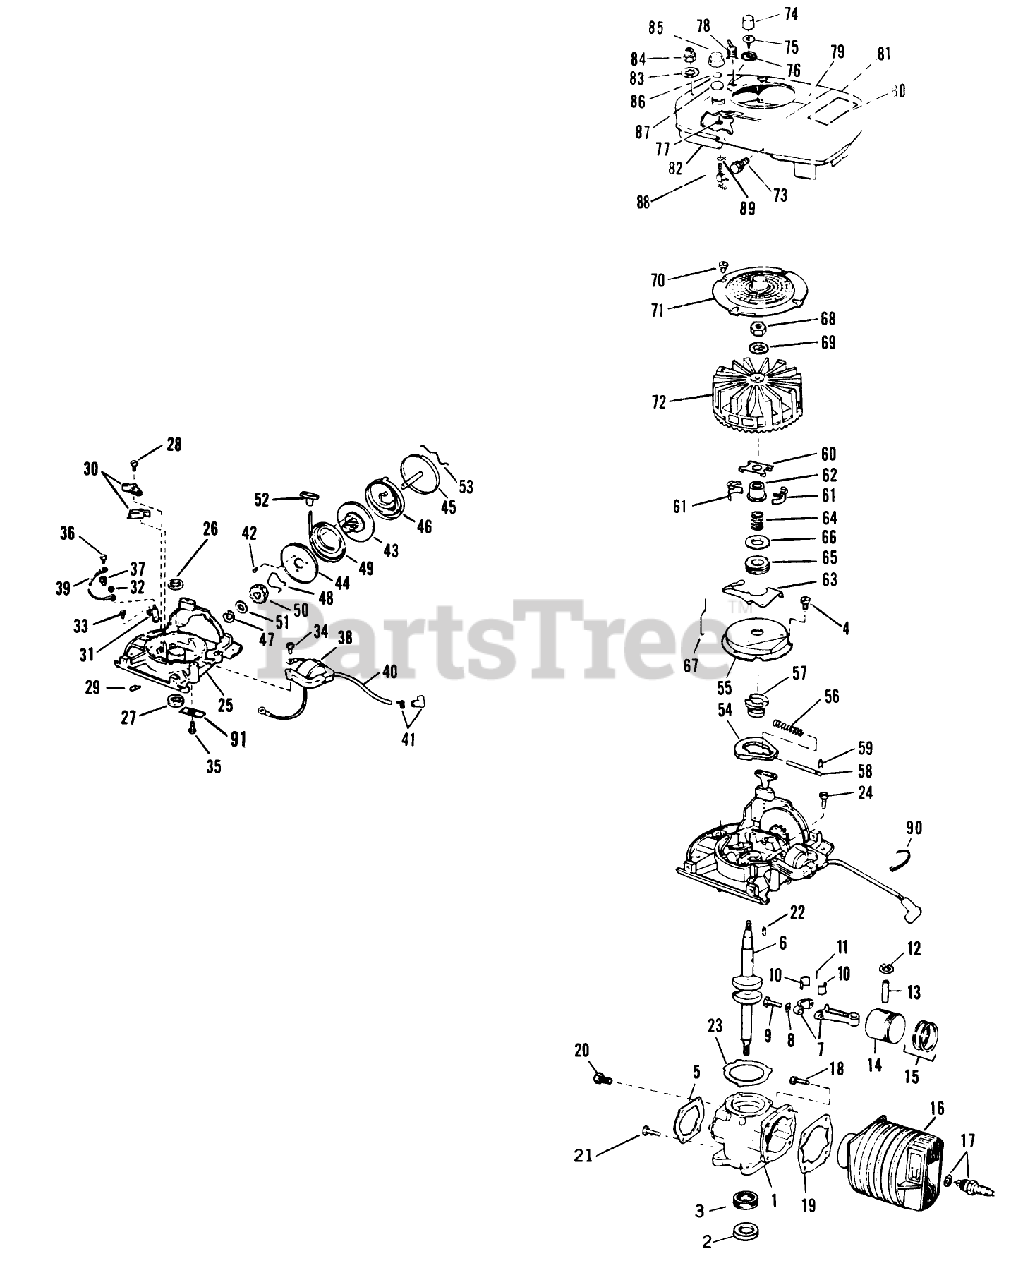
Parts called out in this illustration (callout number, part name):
3	BEARING AY. S
4	SCREW S
5	GASKET S
10	LINER ASM
12	RING-RETAINING
17	Spark Plug Gasket
19	GASKET S
20	SCREW S
21	SCREW S
23	GASKET S
27	BEARING AY. S
30	BREAKER AY. S
35	SCREW S
37	NUT - CLIP
40	LEAD AY. S
42	SCREW S
43	PULLEY STARTER S
46	SPRING S
48	STARTER SPRING S
50	STARTER PINION S
51	WASHER S
53	SPRING S
54	FLYWEIGHT S
55	DUST COVER S
56	SPARK ADV. SPRING S
57	SPARK ADV. S
58	PIN,SPARK ADV. S
59	SPARK ADJ. SPRING
62	COLLAR S
63	LEVER-GOVERNOR S
65	THRUST COLLAR S
70	SCREW F
71	Screen Cup
72	FLYWHEEL S
73	SCREW S
76	CUP-BULB
77	LOCKNUT S
78	SWITCH AY.
84	PALNUT S
85	FUEL CAP AY S
86	BAFFLE - FOAM SM
88	VALVE&SCREEN SM
